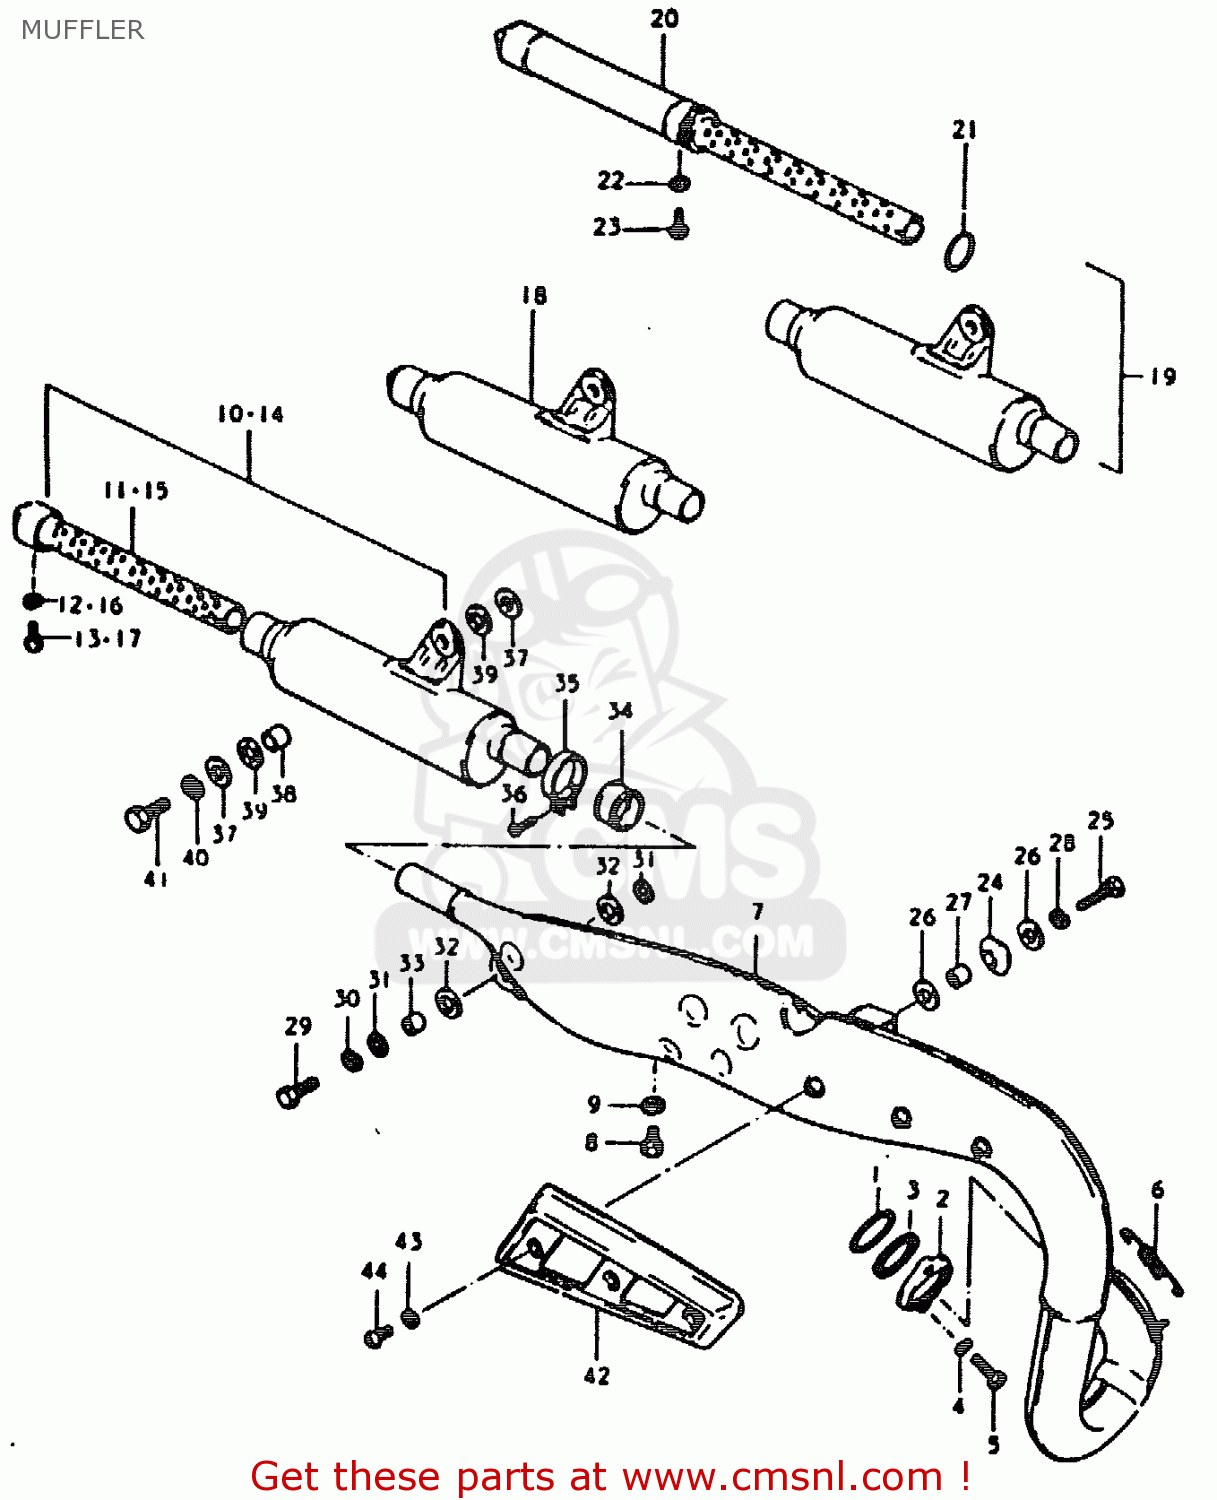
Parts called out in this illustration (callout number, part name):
1	GASKET,EXHAUST PIPE (NAS)
2	CLAMP,EXHAUST PIPE
3	CUSHION,EXHAUST PIPE
4	LOCK WASHER
5	BOLT
6	SPRING
7	MUFFLER, 1ST
8	BOLT 10X9
9	GASKET(10X14X3.6) (NAS)
10	MUFFLER ASSY, 2ND
11	PIPE,BAFFLE
12	LOCK WASHER
13	SCREW
24	DAMPER,MUFFLER,FR
25	BOLT
26	WASHER
27	SPACER (8X12X15)
28	LOCK WASHER
29	BOLT
30	LOCK WASHER
31	WASHER (8.2X20X1.6)
32	CUSHION
33	SPACER (8.6X13.8X9.8)
34	CONNECTOR,MUFFLER
35	CLAMP
36	SCREW
37	WASHER
38	SPACER
39	CUSHION
40	LOCK WASHER
41	BOLT
42	COVER,MUFFLER
43	LOCK WASHER
44	SCREW
